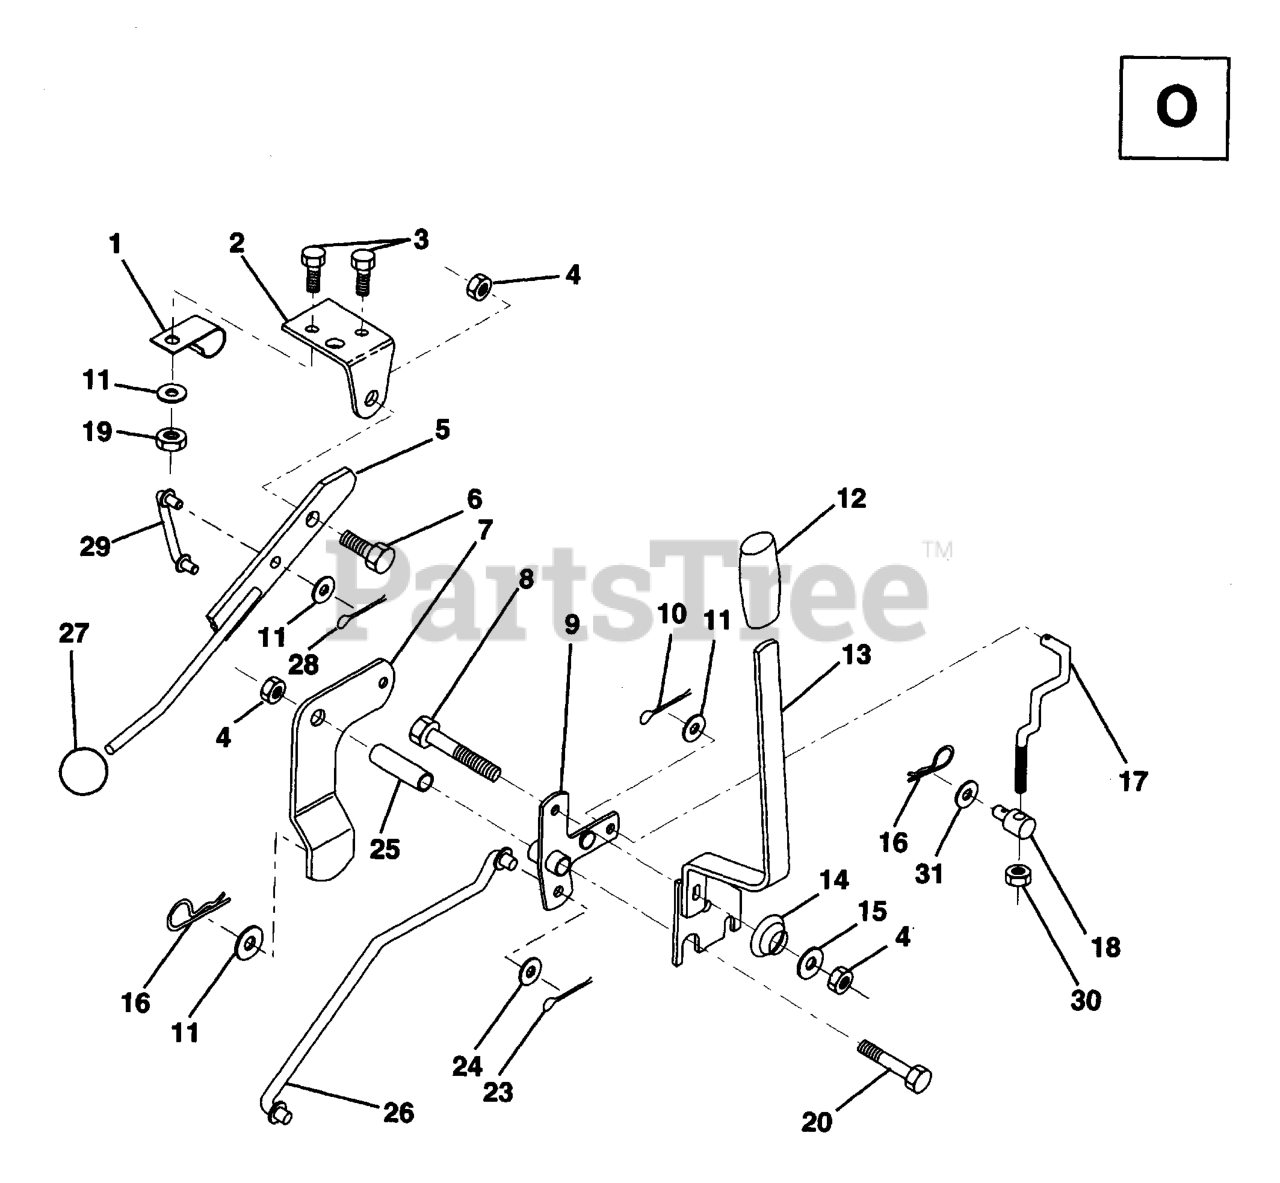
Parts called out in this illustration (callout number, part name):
1	CLIP,INSULATOR
2	BRKT CLUTCH
3	BOLT
5	CLUTCH LEVER
6	BOLT, SHOULDER LT
7	ASSEMBLY MOWER CLUTCH ARM
9	BELLCRANK,LIFT
10	COTTER PIN
11	WASHER
12	GRIP HANDLE
13	LIFT HANDLE ASSY
14	SPRING COMPRESSIO
15	WASHER T
16	SPRING TI
17	LINK LIFT FRT
18	TRUNNION.ADJUSTABLE.3/8-16
19	NUT.CROWNLOCK.1/4
23	PIN COTTER
24	WASHER GT
25	TUBE SPACER
28	COTTER PIN
29	LINK MOWER CLUTCH
30	NUT
31	WASHER
